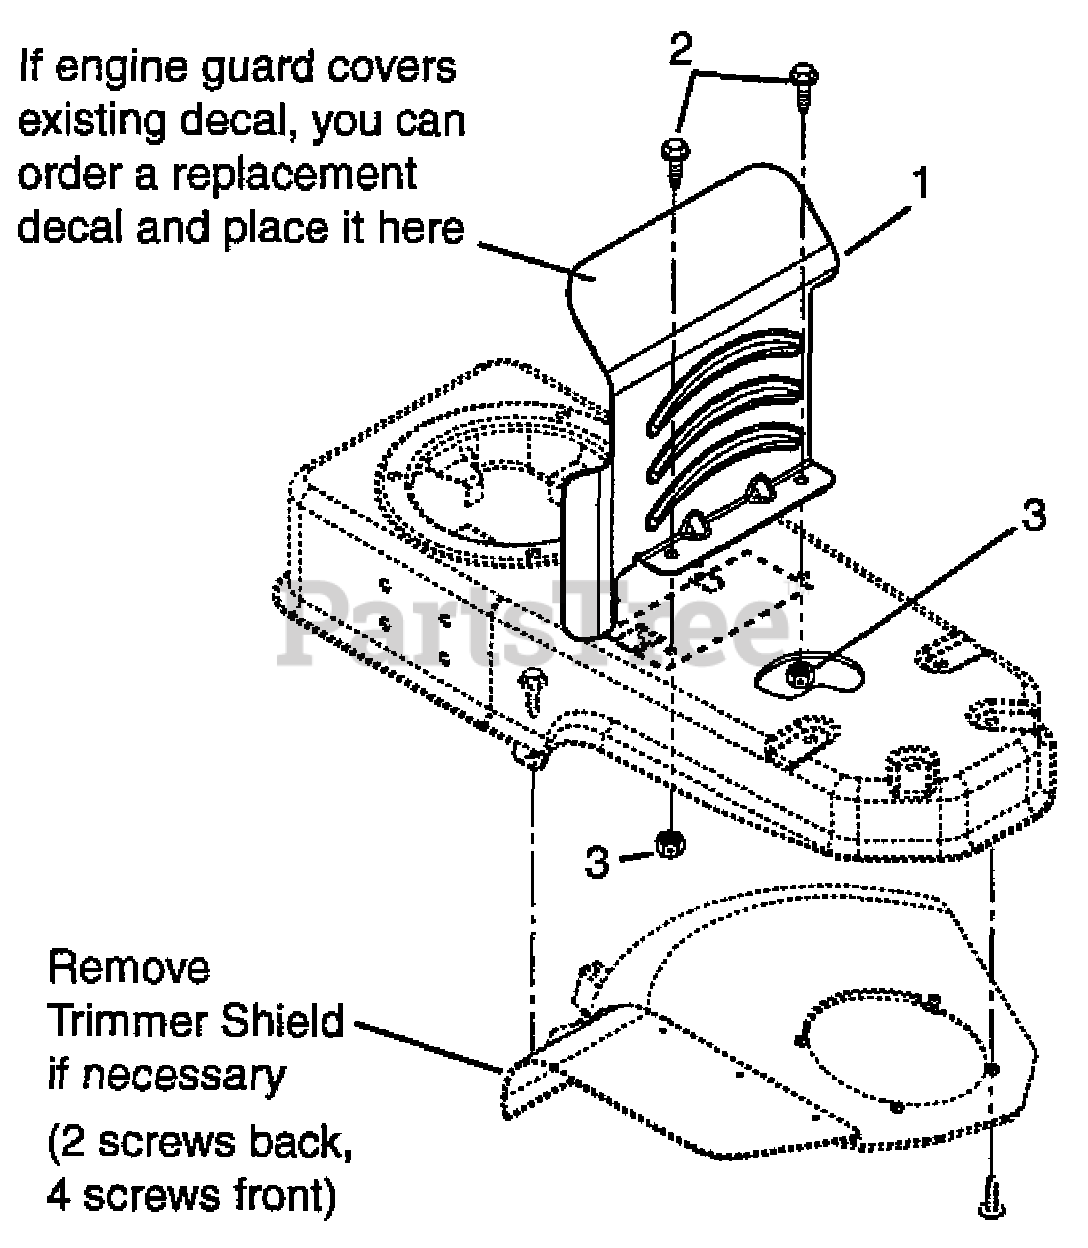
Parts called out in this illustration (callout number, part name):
1	SHIELD- ENGINE
2	@SCR-TAP .38-16X.50 HWH TR YWZ
3	@NUT-LK-CTR .38-16 YWZC
